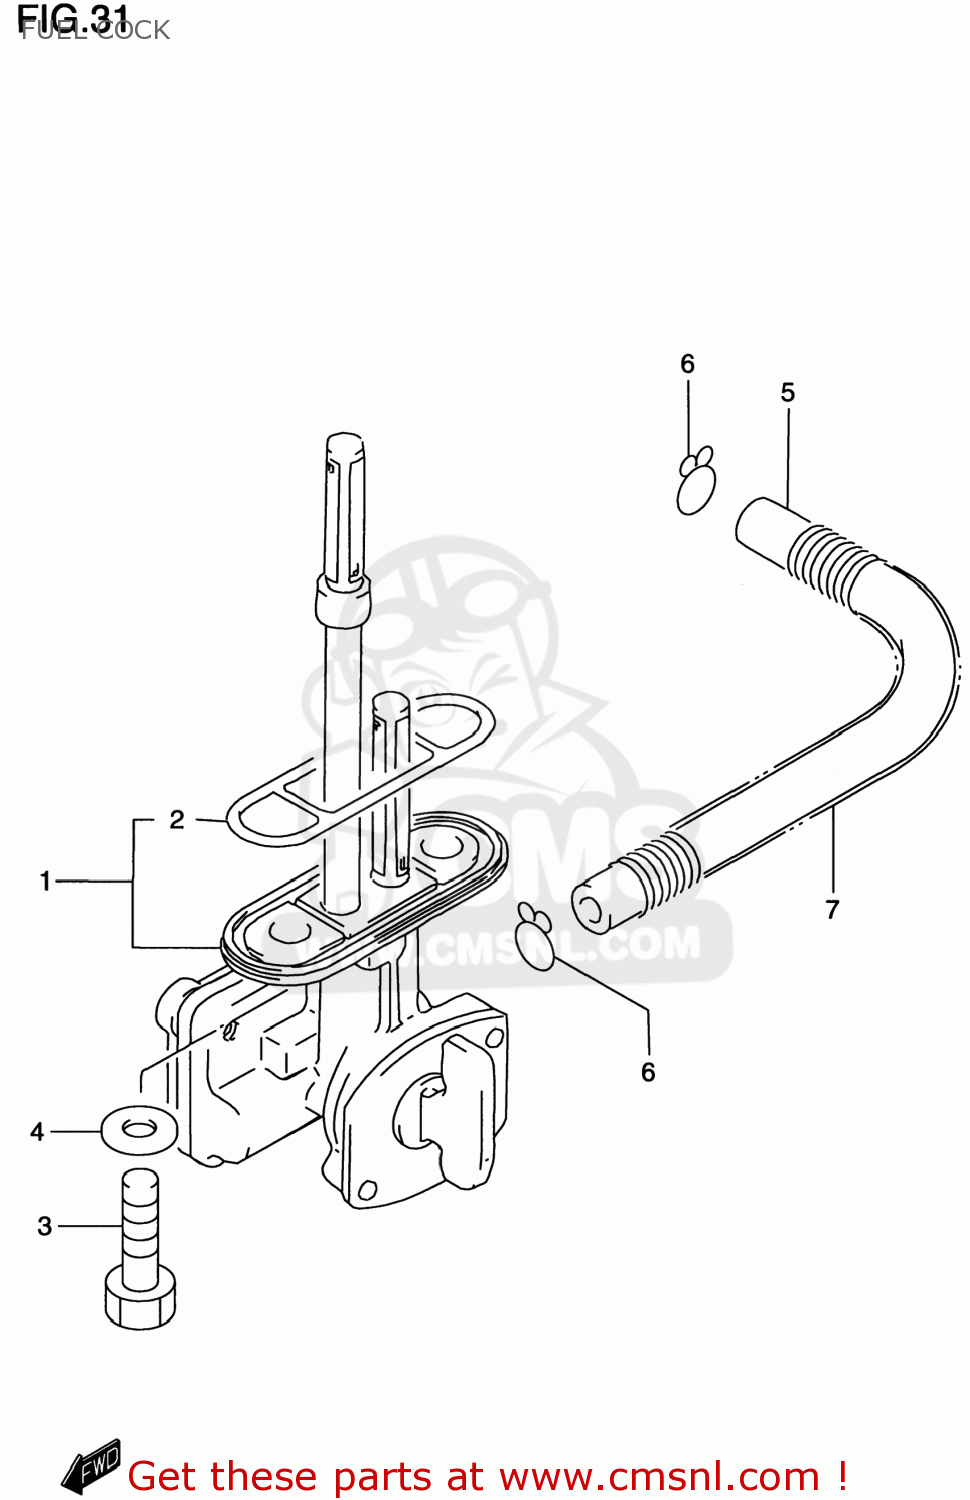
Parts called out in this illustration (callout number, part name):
1	COCK ASSY,FUEL
2	GASKET,JOINT (NAS)
3	BOLT(6X20)
4	GASKET(6.4X11.5X0.8) (NAS)
5	HOSE(5X8.2X600)
6	CLIP
7	SPRING
